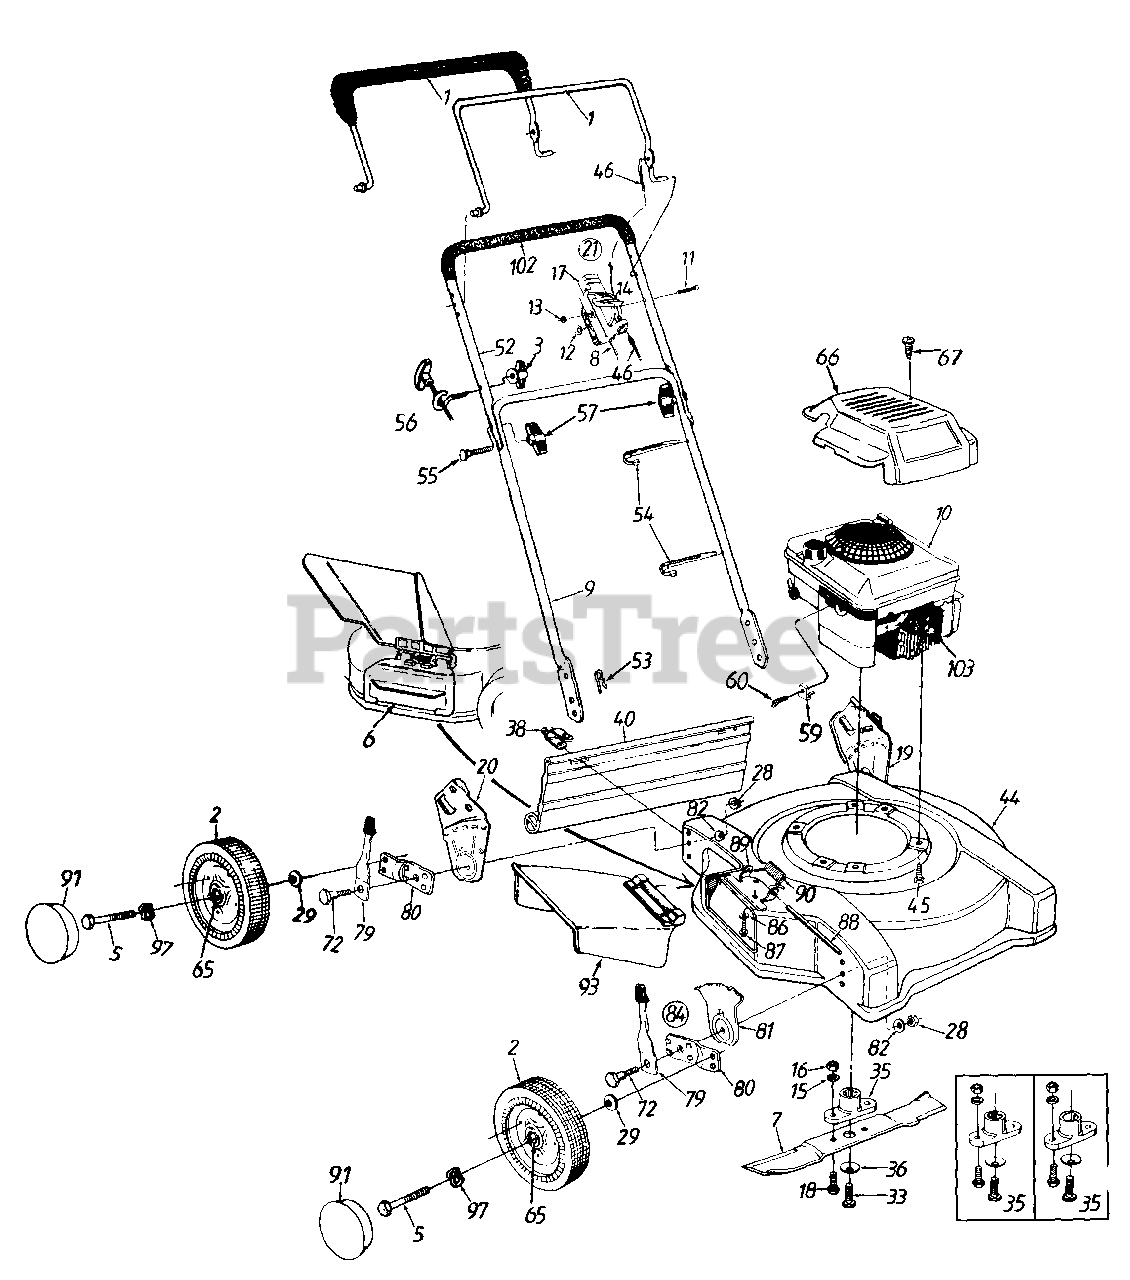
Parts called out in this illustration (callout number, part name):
2	Wheel Ass'y. Comp. (Yellow Rim)
3	Wing Nut 1/4-20 Thd.
5	Axle Bolt
6	Mulching Plug
7	Mulching 20" Blade
8	Throttle Control Wire - 51"
10	Engine
11	Oval C-Sunk Mach. Scr.
12	Spr. Wash..66" I.D.
13	Hex L-Nut 1/4-20 Thd.
14	Throttle Lever
15	L-Wash. 3/8" I.D.
16	Hex Nut 3/8-24 Thd.
17	Throttle Body
18	Hex Bolt 3/8-24 x 1.0" Lg.
19	Wheel Brkt. Ass'y. - L.H.
20	Wheel Brkt. Ass'y. - R.H.
21	Throttle Box Comp.
28	Hex Nut 3/8-16 Thd.
29	Bell-Wash..40" I.D. x .88"
33	Hex Bolt 3/8-24 x 1.5" Lg.
35	Blade Adapter Kit (Keyed)
36	Bell-Wash..39" I.D.
38	Hinge Clip
40	Rear Flap Ass'y.
44	20" Deck Ass'y
45	Mex Wash. Hd. TT-Tap Scr. 3/8-16 x 1.00" Lg.
46	Control Cable - 39"
54	Cable Tie
55	Curved Hd. Bolt 5/16-18 x 2" Lg.
56	Rope Guide
57	Hand Knob
59	Cable Clamp
60	Hex Wash Hd. Scr. #10-32 x .62" Lg.
65	Wheel Bearing
66	Engine Shroud
67	Screw #10 x 1.25" Lg.
72	Shoulder Bolt .50" Dia.
79	Spring Lever Ass'y. w/Knob
81	Height Adj. Plate
82	Bell-Wash..39" I.D. x 1.38"
84	Front Height Adj. Ass'y. Comp - R.H.
86	Bell-Wash .285" I.D. x .75" O.D.
87	Hex Wash. Hd. Tap Scr. 1/4-20 x .5" Lg
88	Hinge Pin
89	Adapter Plate
90	Torsion Spring
91	Hub Cap
93	Chute Deflector Ass'y Comp.
97	Wave Washer .53" I.D.
102	Foam Grip
103	Spark Plug Boot
